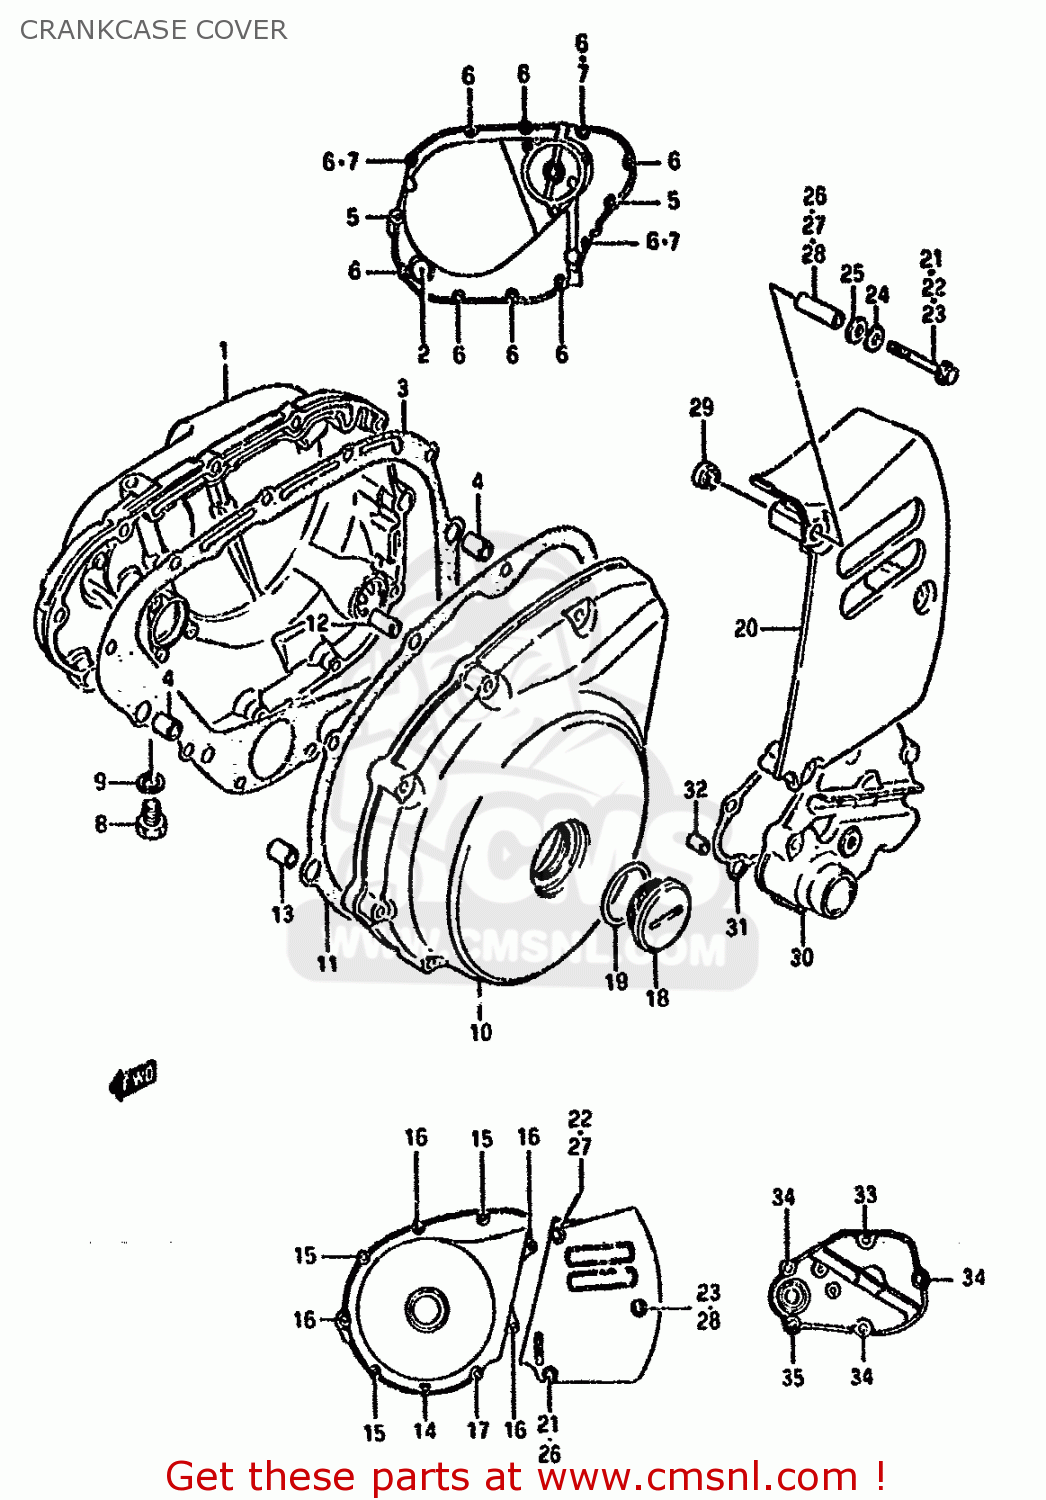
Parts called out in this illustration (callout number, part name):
1	COVER,CLUTCH
2	LENS,OIL LEVEL CHECK
3	GASKET,CLUTCH COVER (NAS)
4	PIN
5	BOLT
6	BOLT
7	GASKET(5.8X13X1.2) (NAS)
8	PLUG
9	GASKET(12.1X16.2X3.7) (NAS)
10	COVER,GENERATOR
11	GASKET,GENERATOR COVER (NAS)
12	PIN
13	PIN
14	BOLT
15	BOLT
16	BOLT
17	BOLT
18	PLUG,36X10
19	O RING(D:3.1,ID:32.7)
20	COVER,ENGINE SPROCKET
21	BOLT
22	BOLT
23	BOLT
24	WASHER
25	WASHER(8.7X15X2.1)
26	SPACER (6.1X9X31.5)
27	SPACER (6.1X9X38.3)
28	SPACER (6.1X9X41.3)
29	WASHER(8.7X16X5)
30	COVER,GEAR SHIFT
31	GASKET,GEAR SHIFT COVER (NAS)
32	PIN
33	BOLT
34	BOLT
35	BOLT
